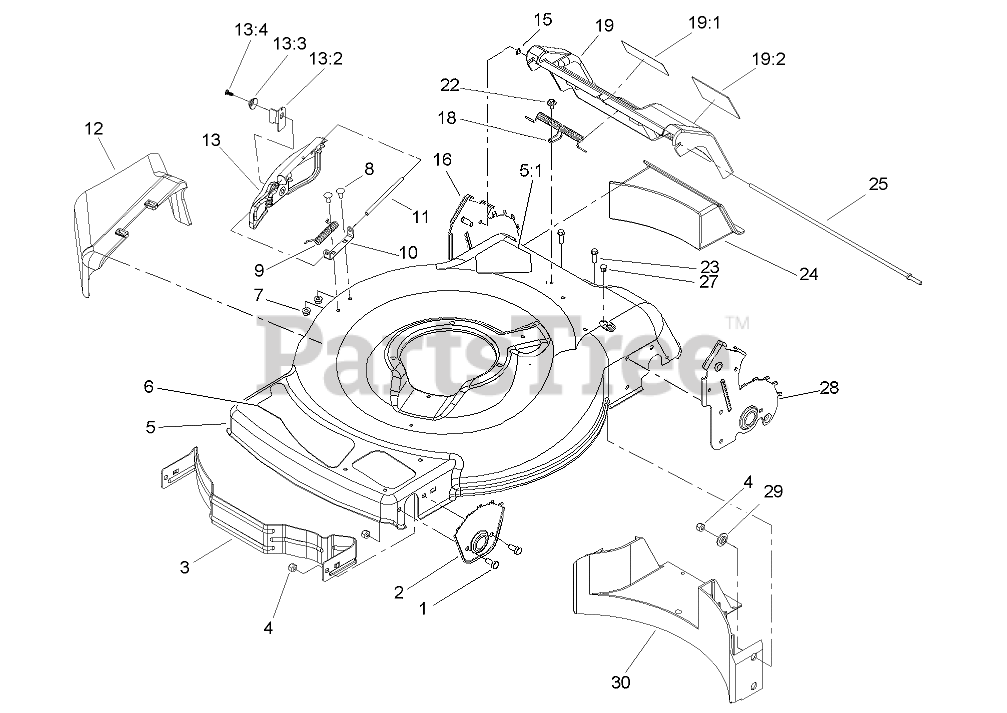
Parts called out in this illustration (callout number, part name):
1	SCREW-HH
2	Plate-HOC, Front
3	Baffle-Front
4	NUT-LOCK, NI
5	HOUSING
5:1	DECAL-DANGER
6	Decal-Deck
7	NUT-HHF
8	SCREW-CARR
9	SPRING-TORSION
10	BRACKET-COVER
11	ROD-COVER
12	CHUTE-DISCHARGE, SIDE
13	DISCHARGE DOOR ASM
13:2	LATCH-DOOR
13:3	CAP-DOOR
13:4	SCREW-PLASTITE
15	NUT-PUSH
16	RH REAR HOC PLATE ASM
18	Spring-Door, Rear
19	REAR DOOR ASM
19:1	DECAL-WARNING
19:2	DECAL-WARNING
22	SCREW AND WASHER ASM
23	SCREW-HWH
24	Plug-Discharge, Rear
25	Rod-Pivot, Rear Door
27	Plug-Dome
28	LH REAR HOC PLATE ASM
29	Washer-Stepped
30	Baffle-Rear
